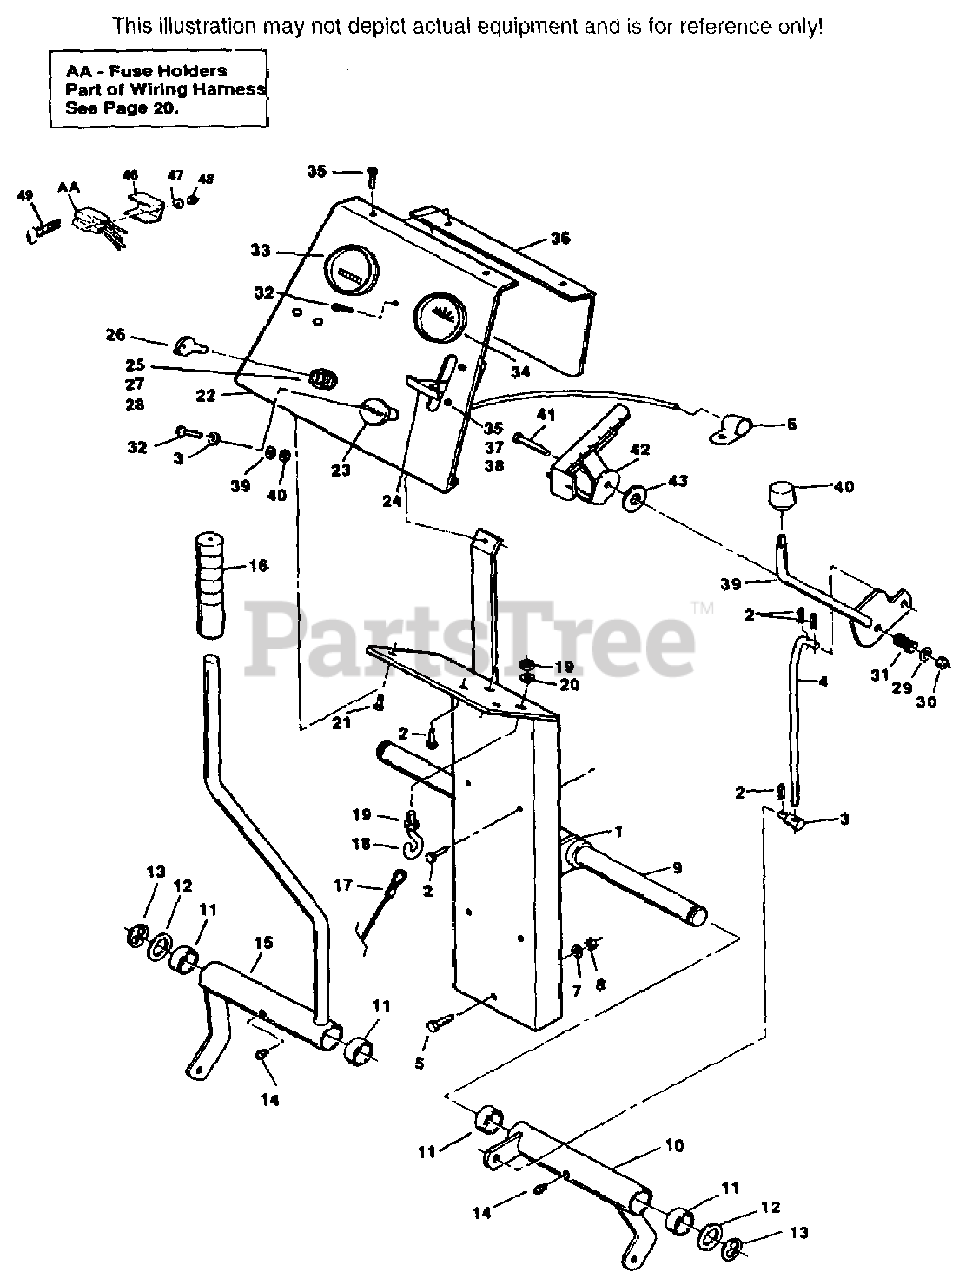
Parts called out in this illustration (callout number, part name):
1	CONSOLE SUPPORT
2	HAIR PIN COTTER, LARGE
3	SWIVEL JOINT
4	SHIFT CONNECTOR ROD
6	CLAMP, CABLE
7	LOCKWASHER, 5/16 SPRING
9	BELLCRANK SHAFT
10	SHIFTER ASSEMBLY(INCLUDES 11 & 14)
11	BRONZE BEARING
12	WASHER, 49/64 X 1-1/4 X 16 GA.
13	RETAINING RING, 3/4 EXT. "E"
14	GREASE FITTING, 1/4-28 STR
15	MOWER ENGAGE(INCLUDES 11, 14, 16)
16	GRIP, MOWER LEVER
17	WINCH CABLE ASSEMBLY
18	EYEBOLT, 3/8-16 X 2"
20	LOCKWASHER, 3/8 SPRING
22	INSTRUMENT PANEL
23	CHOKE CONTROL
24	THROTTLE CONTROL
25	STARTER SWITCH(INCLUDES 26-28)
26	KEY, IGNITION
27	LOCKWASHER, INTERNAL TOOTH 5/8"
28	HEX NUT, 5/8-11
29	WASHER, 13/32 X 13/16 X 16 GA.
30	HEX NUT, 3/8-16 ELASTIC STOP
31	SPRING
33	HOUR METER
34	AMMETER
36	PANEL COVER WELDMENT
39	SHIFTER HANDLE
40	SHIFTER KNOB
42	SHIFT QUADRANT WELDMENT
43	WASHER, 3/8 X 2 X 16 GA.
46	BRACKET, FUSE HOLDER
47	LOCKWASHER, #10 EXTERNAL TOOTH
48	HEX NUT, ELASTIC STOP LOCK #10-32
